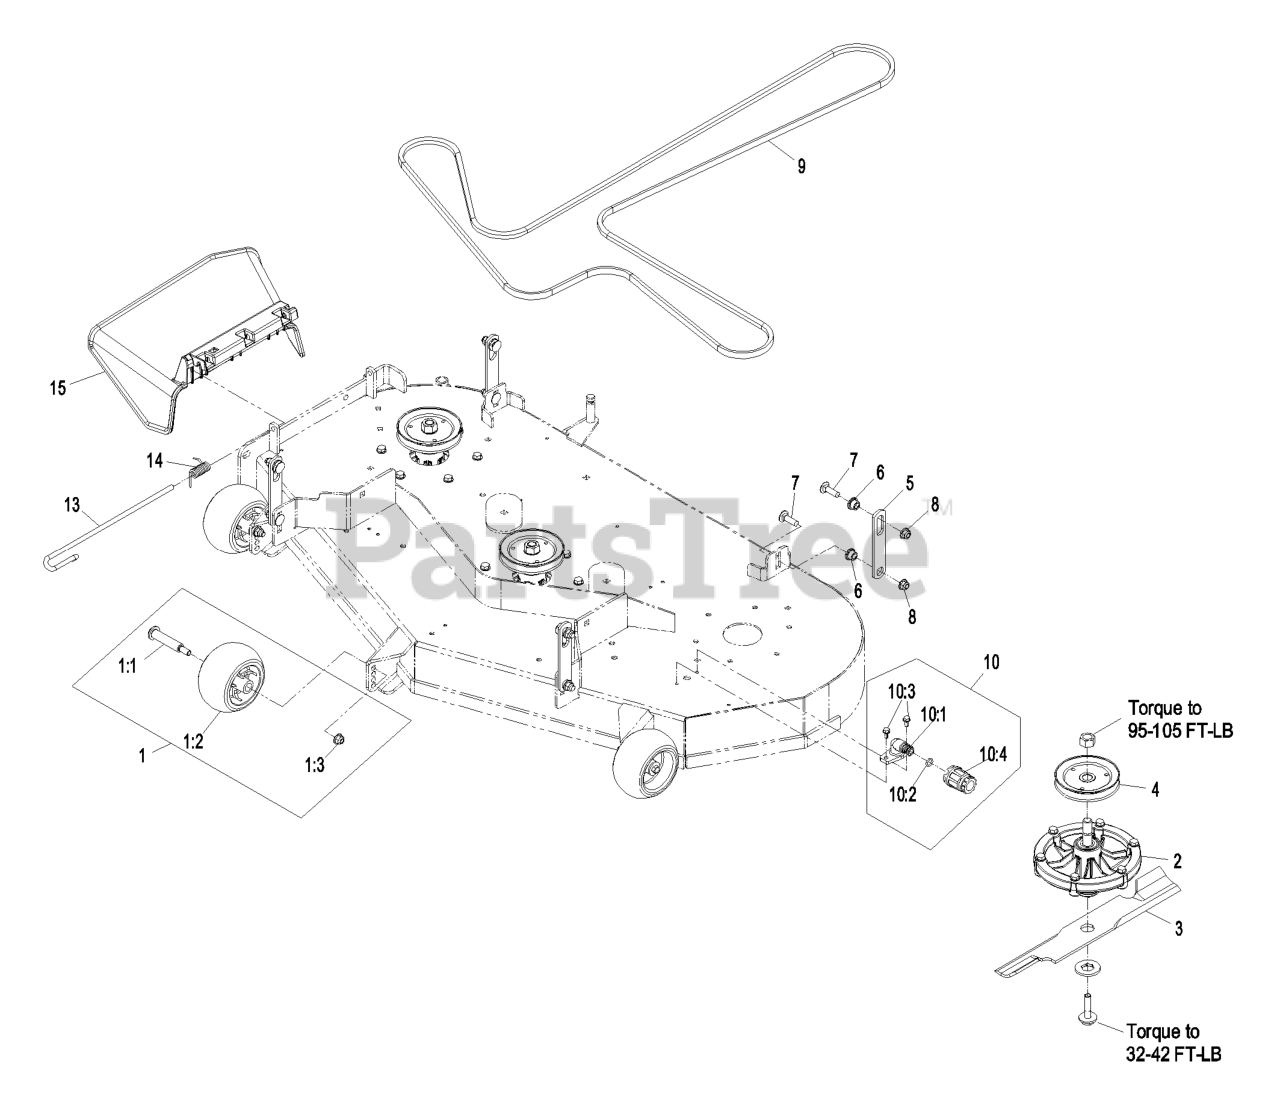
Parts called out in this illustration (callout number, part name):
1	ANTI-SCALP ROLLER KIT
1:1	BOLT-SHOULDER
1:2	ROLLER-SCALP, ANTI
1:3	NUT-HF, NI
5	HANGER-DECK
6	BUSHING-FLANGED
7	BOLT-CARR
8	NUT-HF, NI
9	BELT
10	WASHOUT PORT KIT
10:3	SCREW-HWH
10:4	CONNECTOR-HOSE
13	PIN-CHUTE
14	SPRING-TORSION
15	CHUTE DEFLECTOR XRK M056
